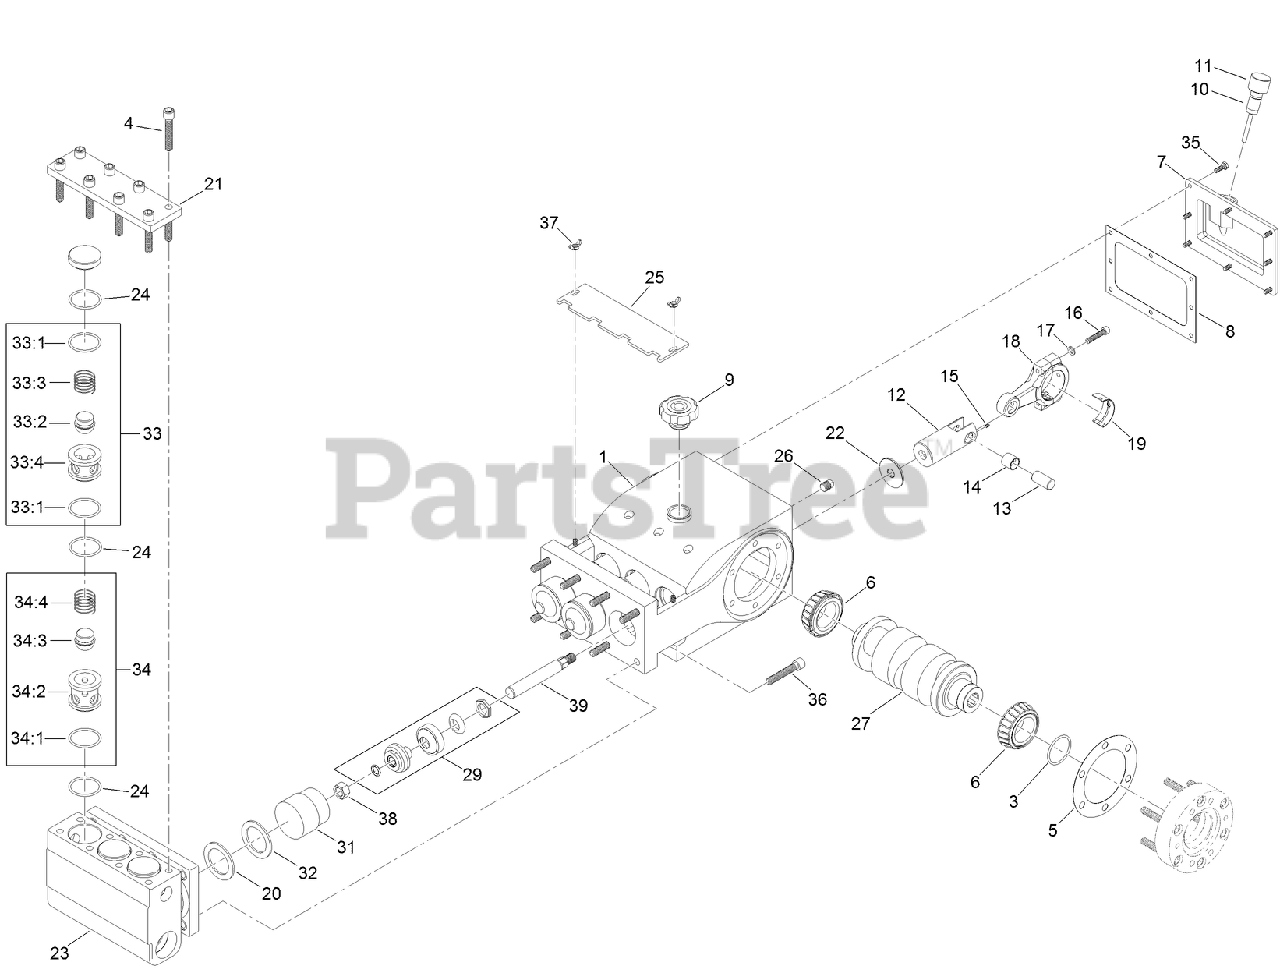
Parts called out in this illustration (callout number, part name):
1	CASE-PUMP
3	SEAL-OIL, CRANKSHAFT
4	CAPSCREW
5	SHIM-ADJUSTING, MAIN BEARING
5	SHIM-BEARING, MAIN (.015)
5	SHIM-BEARING, MAIN (.010)
6	BEARING-MAIN
7	COVER-PAN
8	GASKET-COVER, PAN
9	CAP-BREATHER, OIL FILLER
10	VENT-CASE, PUMP
11	DIPSTICK-FILLER, OIL
12	CROSSHEAD
13	PIN-WRIST
14	BUSHING-PIN, WRIST
15	SCREW-SET, WRIST PIN
16	CAPSCREW-ROD, CONNECTING
17	WASHER-CAPSCREW, CONNECTING ROD
18	ROD-CONNECTING
19	BEARING-INSERT, CONNECTING ROD
20	SEAL-OIL, CROSSHEAD
21	COVERPLATE-PLUG
22	WASHER-PLUNGER
23	DUCTILE-END, FLUID
24	O RING-SEAT, VALVE
25	COVER-CHAMBER, PISTON
26	PLUG-DRAIN, OIL
27	CRANKSHAFT-DRIVE, SPLINED
29	HSN PISTON KIT
29	GOLD PISTON KIT
31	LINER-PISTON, CHROME
31	LINER-PISTON, CERAMIC
32	GASKET-LINER
33	DISCHARGE VALVE ASM
33:1	O RING-SEAT, VALVE
33:2	VALVE-BODY
33:3	SPRING-VALVE
33:4	SEAT-VALVE, DISCHARGE
34	SUCTION VALVE ASM
34:1	O RING-SEAT, VALVE
34:2	SEAT-VALVE, SUCTION
34:3	VALVE-BODY
34:4	SPRING-VALVE
35	CAPSCREW-COVER, PAN
36	CAPSCREW-FLUID, END
37	NUT-WING, INSPECTION COVER
38	NUT-LOCK, PISTON ROD
39	ROD-EXTENSION, PISTON
